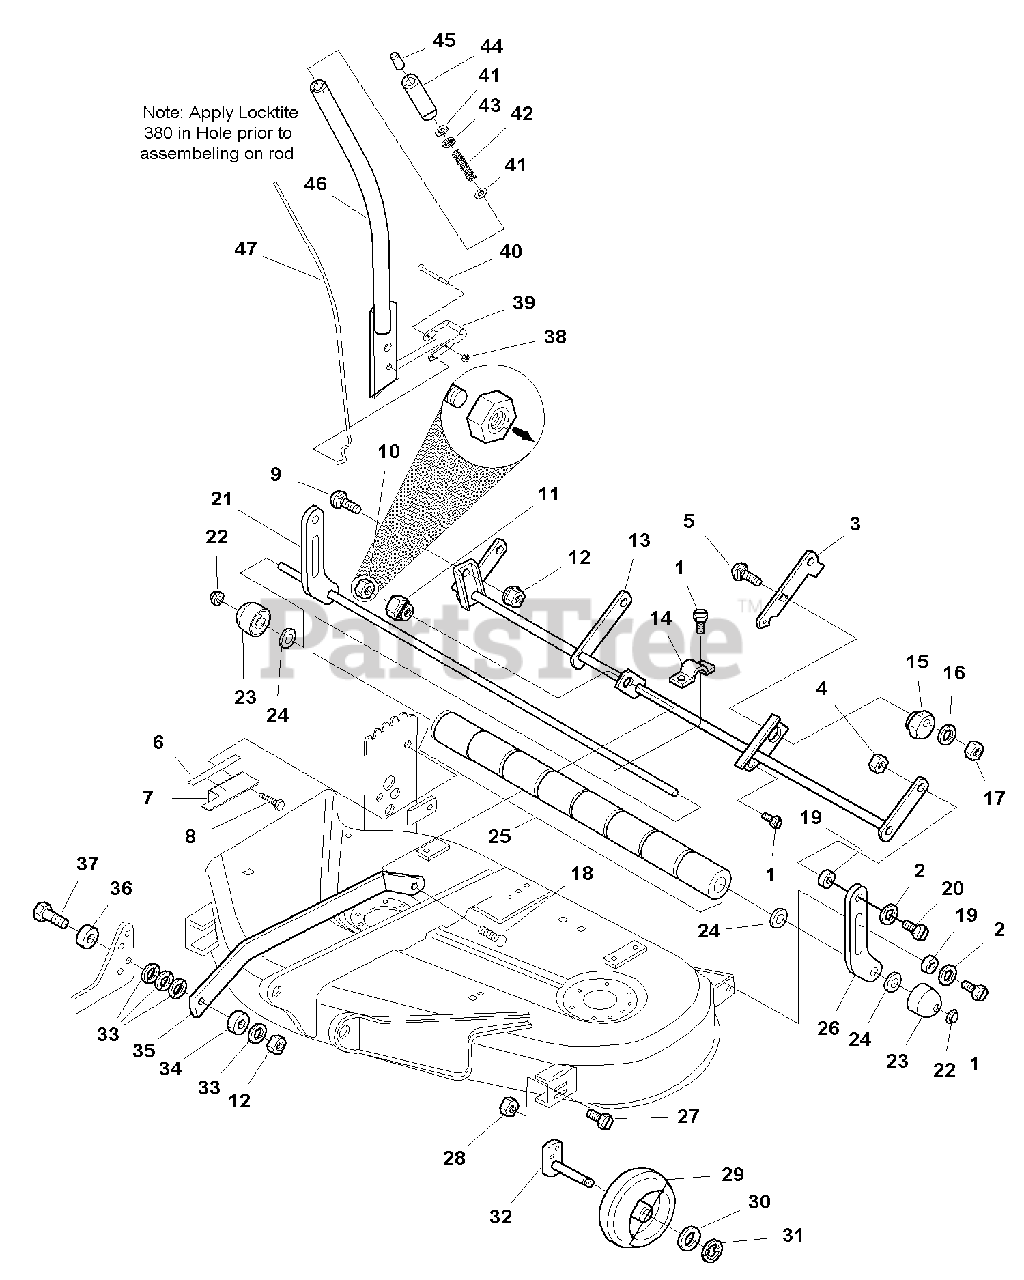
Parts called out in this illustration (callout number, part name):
1	CAPSCREW, Taptite Hex Washer Head, 5/16-18 x 3/4
2	WASHER, 5/16
3	ARM ASSEMBLY
4	NUT, Hex Lock, 5/16-18
5	CARRIAGE BOLT, 5/16-18 x 1-1/4
6	DECAL, Height of Cut
7	BRACKET, Decal
8	CAPSCREW, Hex Head, Taptite, 5/16-18 x 1/2
9	CARRIAGE BOLT, 3/8-16 x 1
10	* NUT, Hex Lock, Alum Insert, 3/8
11	NUT, Hex Adjusting, .99 DIA .687
12	NUT, Hex Lock, 3/8-16
13	ARM ASSEMBLY, Rocker
14	STRAP
16	WASHER, 5/16
17	NUT, Hex, Flange Collar Lock, 5/16-18
18	CARRIAGE BOLT, 3/8-16 x 1-1/2
20	CAPSCREW, Hex Head, 5/16-18 x 1
21	SHAFT ASSEMBLY
22	PUSHNUT, 5/8
23	ROLLER, End
24	WASHER, 5/8
26	BAR, Roller, Support
27	CAPSCREW, Hex Head, 1/4-20 x 3/4
28	NUT, Flange Lock, 1/4-20
29	WHEEL, Gauge
30	WASHER, 1/2
31	E-RING, 1/2
32	ARM ASSEMBLY
33	WASHER, 3/8
37	CAPSCREW, Hex Head, 3/8-16 x 2
38	NUT, Hex Lock ESNA, 1/4-20
40	CAPSCREW, Hex Head, 1/4-20 x 2-1/4
41	WASHER
42	SPRING, Compression
43	PUSH NUT, 1/4" Thread
44	GRIP, Lift Lever
46	HANDLE ASSEMBLY
